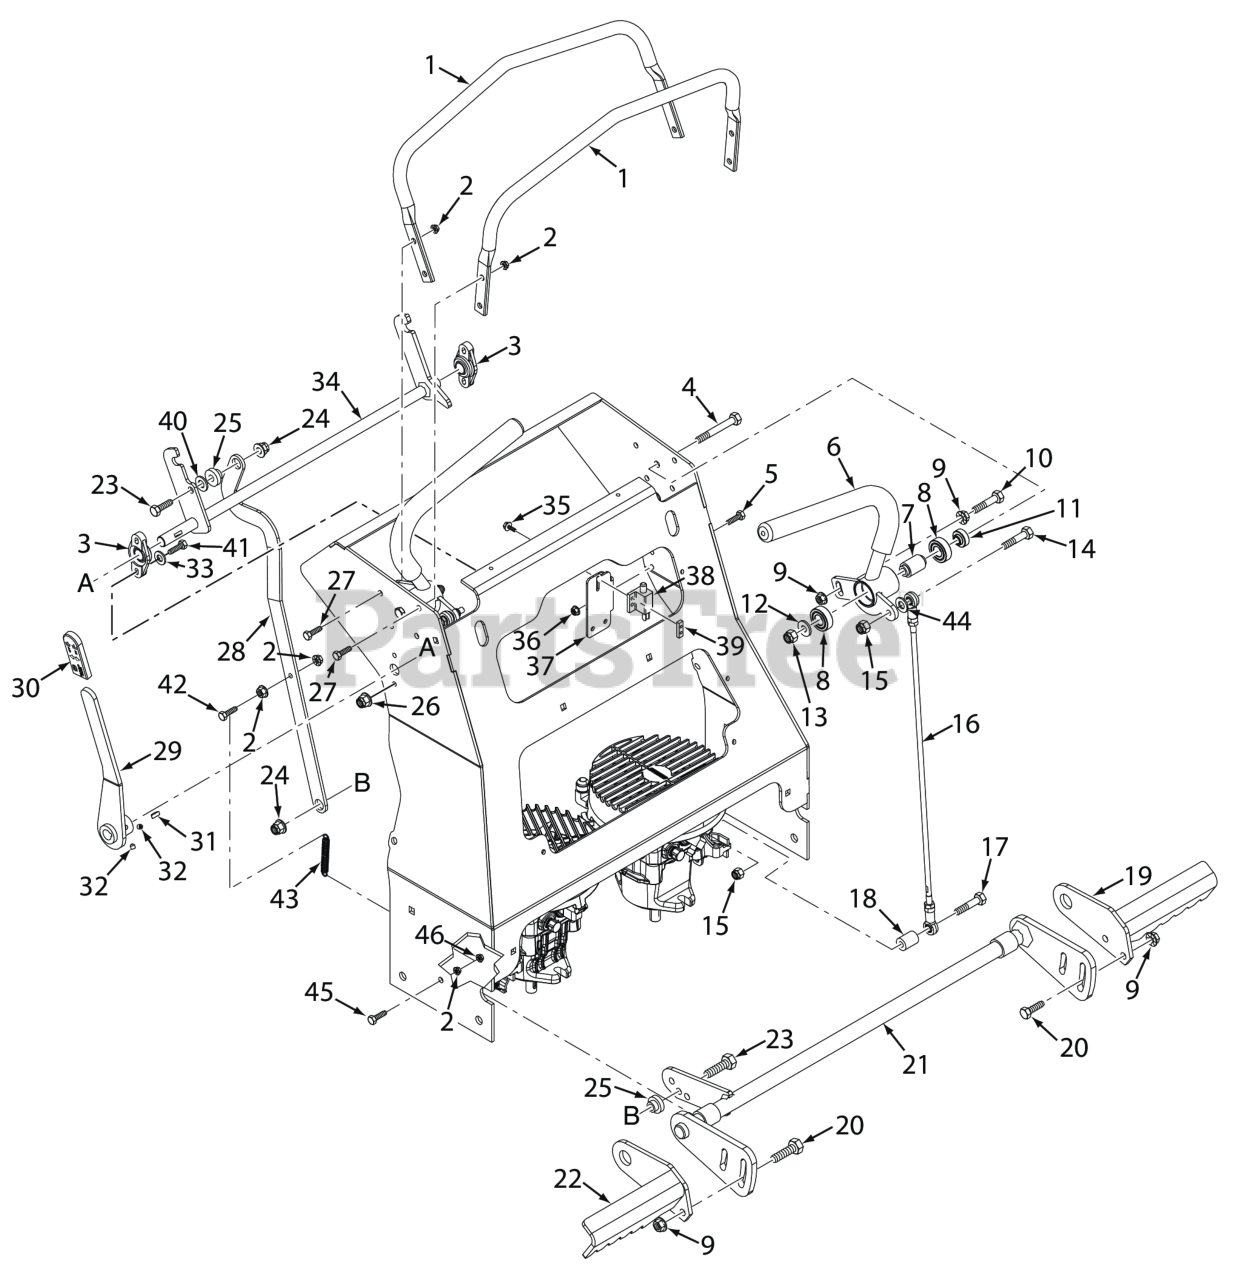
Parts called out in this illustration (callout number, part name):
1	Reference Bar
2	Nut, Serrated Flange 5/16-18 (Right Front Engine Mounting, Briggs and Kohler Only)
3	Bearing
4	Capscrew, Hex Head 3/8-16 x 3.25"
5	BOLT, HEX HEAD, 1/4-20 X 3/4 GR.5
6	Handlebar Assy., LH
6	Handllevar Assy., RH
7	Spacer, Bearing
8	BEARINGS, BALL, NEUTRAL RETURN
9	NUT, 3/8-16 SERRATED FLANGE HEX HEAD
10	Capscrew, Hex Head 3/8-16 x 2.0"
11	Spacer, Controls
12	Flatwasher, 3/8 (.391 x .938 x .105 HD) Grade 8
13	HEX NUT, ELASTIC STOP LOCK, 3/8-16
14	Bolt, 5/16 - 18 x 1 - 1/4" Hex Head
15	HEX NUT, ELASTIC STOP LOCK, 5/16-18
16	Linkage Assy., Steering
17	Hex Head Socket, 5/16-18 x 1" (36)
17	Bolt, Hex Head 5/16-18 x 2-1/2" (x3) (35BV & 37BV-EFI)
18	Spacer (excludes SVRII-36A)
19	Brake Paddle Weldment, RH (36)
19	Brake Paddle Weldment, RH
20	Carriage Bolt, 3/8-16 x 1.0"
21	Bellcrank Weldment, Brake (32/36)
21	Bellcrank Weldment, Brake
22	Brake Paddle Weldment, LH
22	BRAKE PADDLE WLMT, LH
23	Bolt, Hex Head 3/8-16 x 1-1/4", Kawasaki FX / FS
24	Nut, Flange Elastic Stop Nut, 3/8-16
25	BUSHING, BRONZE - .376 ID X .627 OD
26	Nut, Flanged Elastic Stop 1/4-20
27	BOLT, SERRATED FLANGE HEX HEAD 5/16-18 X 3/4"
28	Link, Brank Engage (36)
28	Link, Brake Engage
29	Brake Lever Assy. - SVRII (Incl. #30)
30	Grip, Parking Brake
31	KEY, WOODRUFF #61, 3/16 X 5/8
32	Set Screw 1/4-20 x 1/4"
33	Flatwasher, 1/4 (.281 x .625 x .065)
34	Lock Weldment, Neutral
35	Screw, Hex-Slotted Washer Head #10 32 x 3/4"
36	NUT, 1/4-20 SERRATED FLANGE HEX HEAD
37	Bracket, Neutral Switch
38	Switch, Interlock (see below)
38	Switch, Interlock, Park Brake Normally Open
39	Plate, Threaded
40	Flatwasher, 3/8" Special (.391 x .938 x .105)
41	Capscrew, Hex Head 1/4-20 x 1"
42	Bolt, Hex Head 5/16-18 x 1-1/2" (Right Front Engine Mounting, Briggs and Kohler Only)
43	Spring, Deck Lift
44	Flatwasher, 5/16-.344 x .688 x .065 (48V / 52V)
45	Bolt, Hex Head 5/16-18 x 1-1/2" (Right Front Engine Mounting, Briggs and Kohler Only)
45	Bolt, 5/16 - 18 x 1 - 1/4" Hex Head
46	Nut, Serrated Flange 5/16-18 (Right Front Engine Mounting, Briggs and Kohler Only)
46	Nut, Center Lock, 5/16-18(32)
